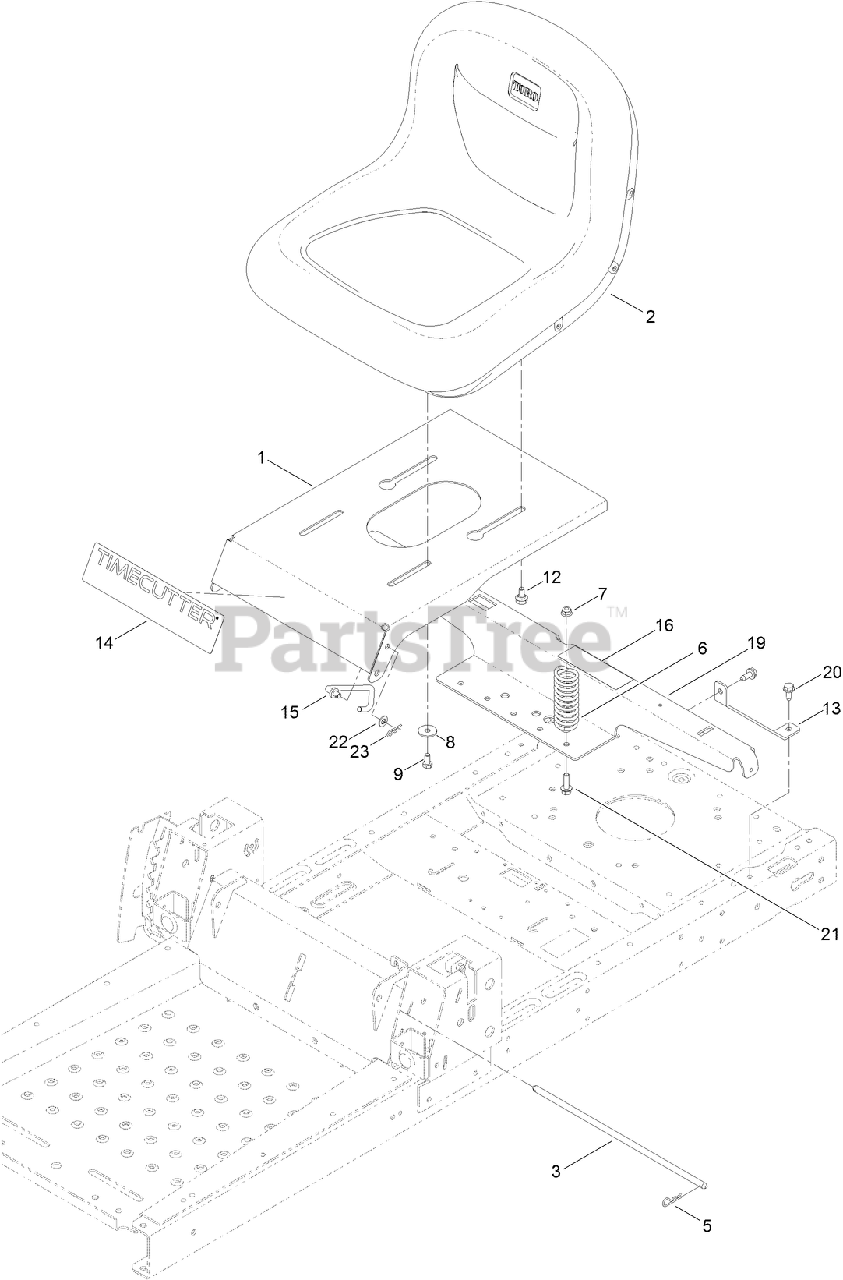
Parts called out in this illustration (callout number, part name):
2	SEAT-15 INCH
3	ROD-PIVOT, NARROW
5	PIN-COTTER
6	SPRING-COMPRESSION
7	NUT-HF, NI
8	WASHER-PIVOT
9	SCREW-HH
12	BOLT-SHOULDER,HFH
13	SUPPORT-TANK, REAR
14	DECAL-TIMECUTTER
15	STOP-SEAT
16	DECAL-SERVICE, CE
19	SUPPORT-POD
20	SCREW-HWHTF
21	SCREW-HHF
22	WASHER-PLAIN
